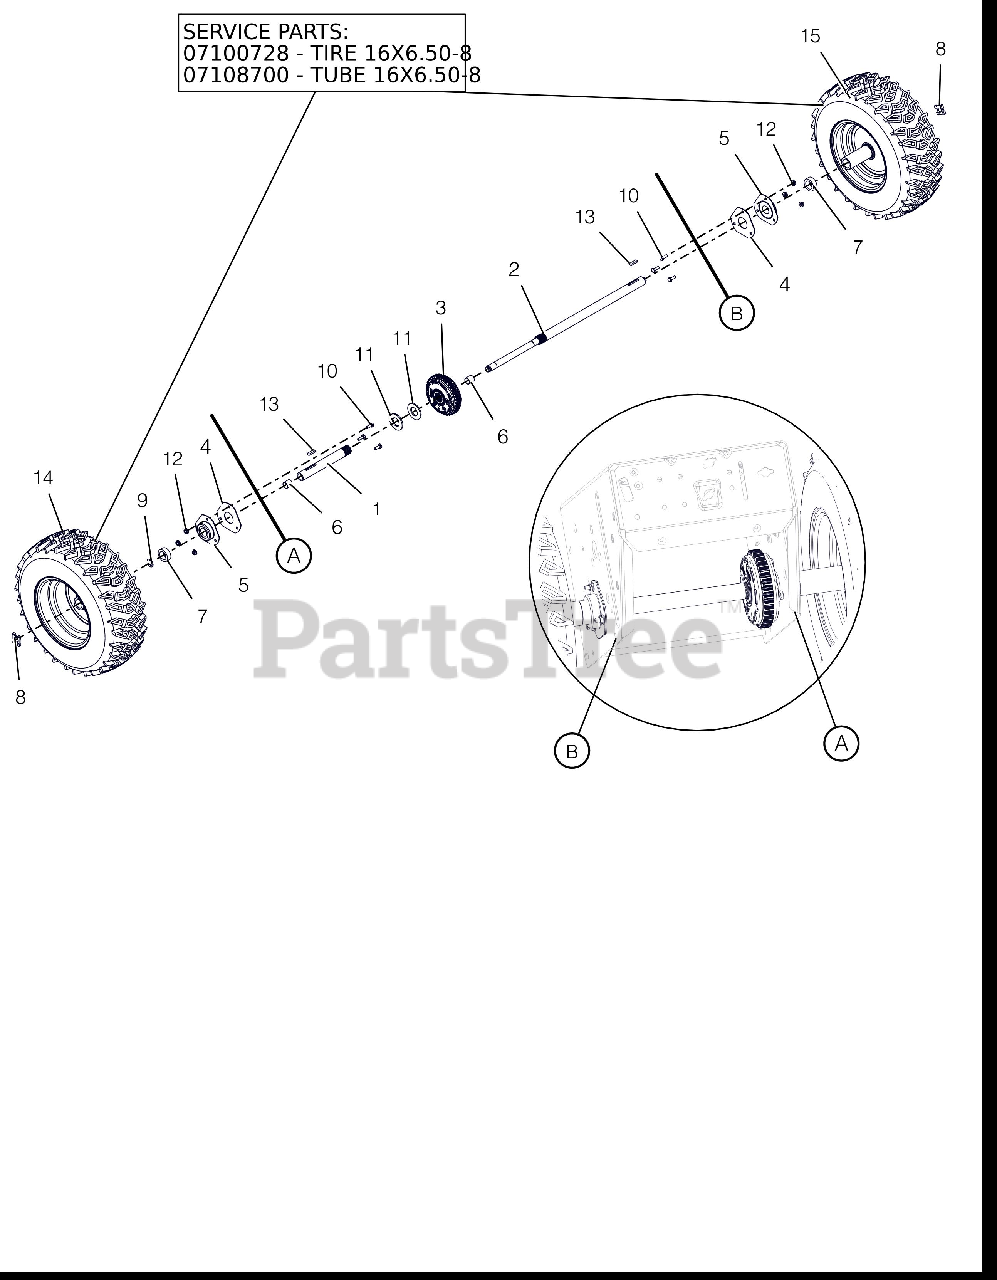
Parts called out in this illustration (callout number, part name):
1	AXLE, SHORT-AUTO W/BUSHINGS
2	AXLE, LONG-PRO AUTO DIFF
3	DIFFERENTIAL, AUTOMATIC
4	PLATE, BEARING SPACER
5	BRG-FLG 1.003/1.000 3 BOLT
6	BSHG-SLV .706X.764X.75 BRZ
7	SPACER, PRO AXLE BEARING
8	CLIP, SNAP .625 DIA
9	RG-RTNG-EXT .625X.042
10	@BLT-HEX .25-20X.75 GR5 YWZC
11	WSHR-FL-STL- 1.062X2.0X.134 YZ
12	@NUT-LK-CTR-FLG .25-20 YWZC
13	KEY-RECT .25X.188X1.00
14	TIRE/WHEEL,RH 16X6.5-8 DIFF T2
14	TIRE, 16X6.50-8 K478
14	TUBE
15	TIRE/WHEEL,LH 16X6.5-8 DIFF T2
